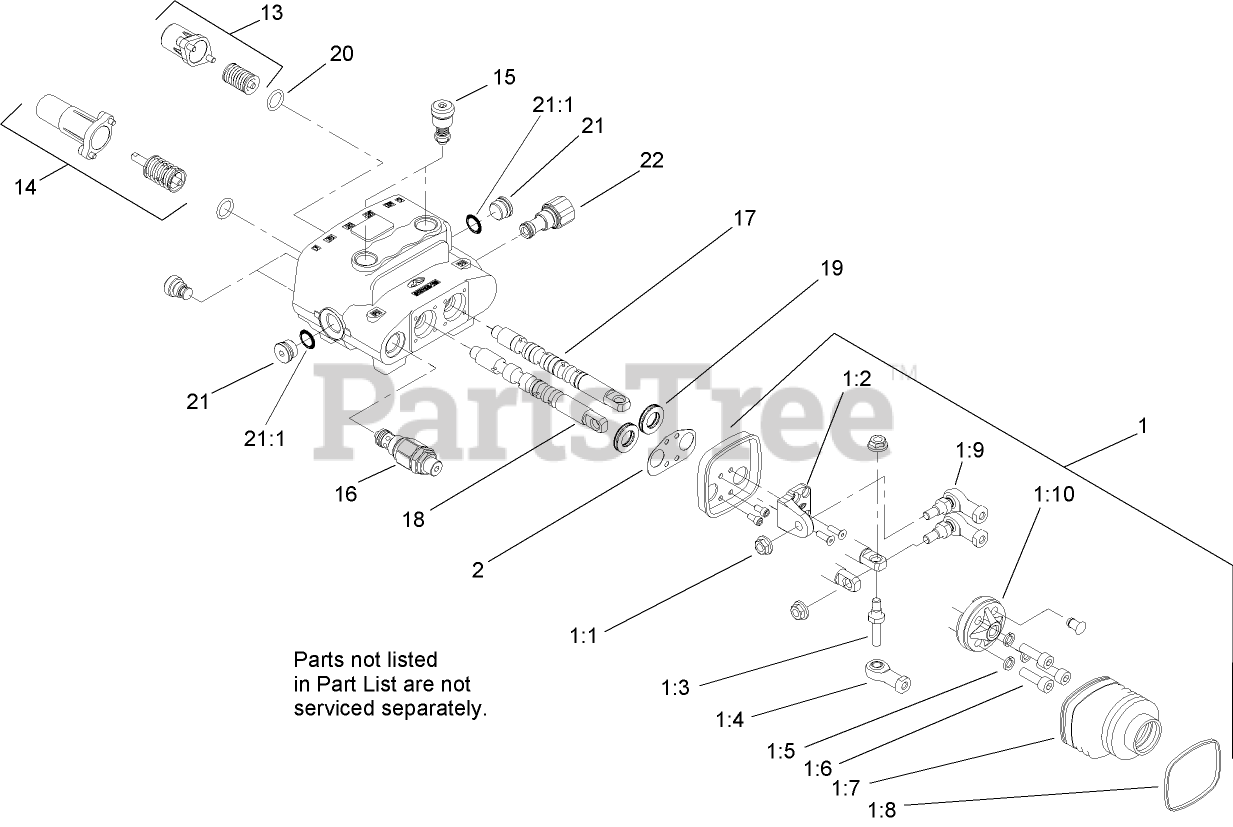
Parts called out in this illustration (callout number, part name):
1	JOYSTICK KIT
1:2	PIVOT-JOYSTICK
1:3	PIN-JOYSTICK
1:4	END-ROD
1:5	WASHER-LOCK, SPRING
1:6	SCREW-HSH
1:7	BELLOW-RUBBER
1:8	TIE-CABLE
1:9	JOINT-JOYSTICK
1:10	HOLDER-ARTICULATED
2	SEAL-JOYSTICK
13	VALVE SPRING KIT
14	DETENT SPRING KIT
15	VALVE-RELIEF, PORT
16	VALVE-RELIEF, MAIN
17	SPOOL-VALVE
18	SPOOL-VALVE
19	SEAL-VALVE, SPOOL
20	SEAL-VALVE
21	PLUG-HEX
21:1	O-RING
22	SLEEVE-PORT, POWER BEYOND
